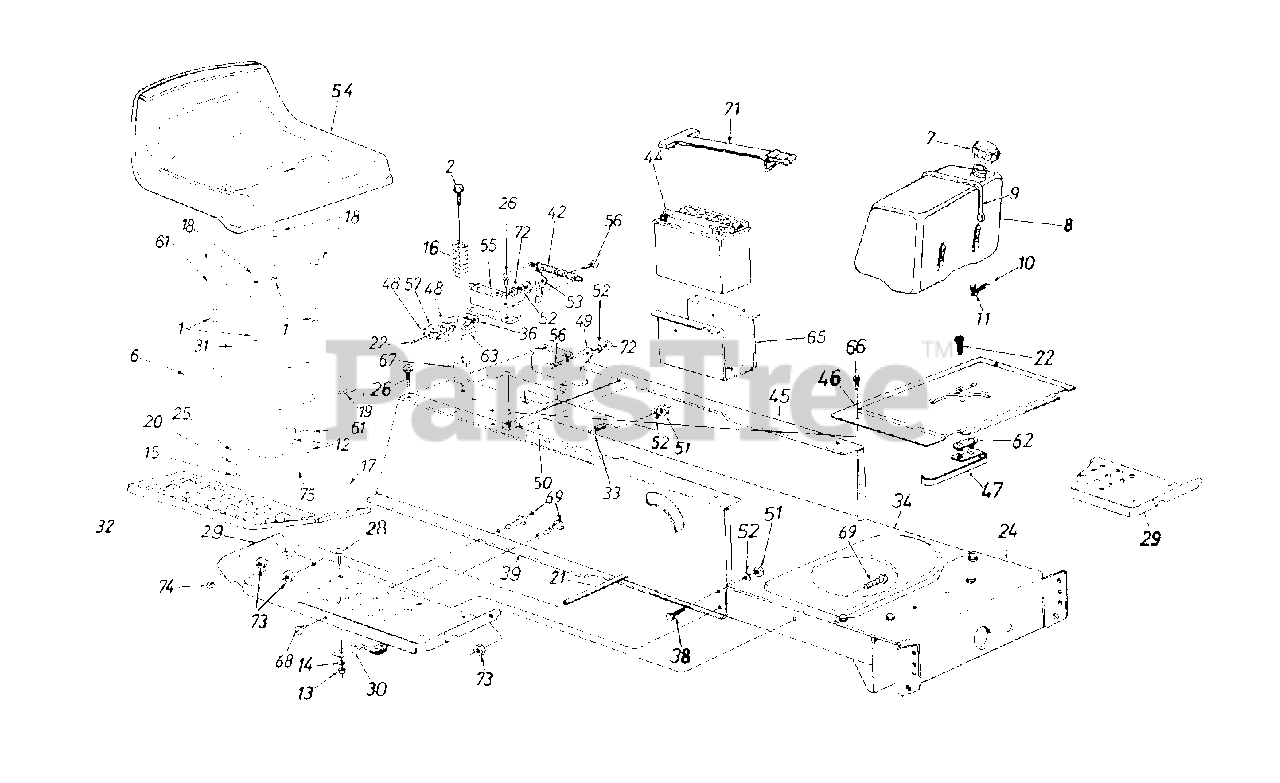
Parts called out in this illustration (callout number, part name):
1	Shoulder Screw 3/8-16 x .5
2	Hex Wash. Hd. Tap Scr. 5/16-18 x 3.25" Lg.
9	Tie Strap
10	Fuel Line
12	Hex B-Tapp Scr. #10-16 x .38
13	Hex Nut 1/4-20 Thd.
14	L-Wash. 1/4" I.D.
15	Lock Nut 1/4-20
16	Compression Spring
19	Compression Spring
20	Spr. Wash. .265 x .562 x .025
21	Running Board Rod
22	Hex Wash. Hd. AB-Tap Scr. #8 x .50" Lg.
25	Fl. Wash. .344 x .62 x .03
26	Hex Wash. Hd. AB-Tap Scr. 5/16 x .75" Lg.
28	Carriage Bolt 1/4-20 x .75"
31	Shld. Bolt 1/4-20 Thd.
32	Rubber Foot Pad-L.H
36	Insulator Boss Plate
38	Hex Bolt 5/16-18 x .75" Lg.
44	12-V Battery
47	Safety Switch (Reverse)
48	Insulator Plate
52	L-Wash. 5/16" I.D.
53	Seat Lift Brkt.
54	Seat - Grey
56	Shld. Bolt .437" Dia. x .268"
57	Spring Switch (Seat-Outer)
61	Seat Selector
62	Insulator Nut Plate
63	Safety Switch (Seat-Inner)
66	Tr. Mach. B-Tap Scr. #10 x .5" Lg.
67	Spring Spacer
68	Truss Mach. Scr. 5/16-18 x .75"
69	Hex Bolt 5/16-18 x .75" Lg.
71	Battery Retainer Strap
72	Hex Nut 5/16-18 Thd.
73	Hex Sems Nut 5/16-18 Thd.
74	Hex Sems Nut 1/4-20 Thd.
